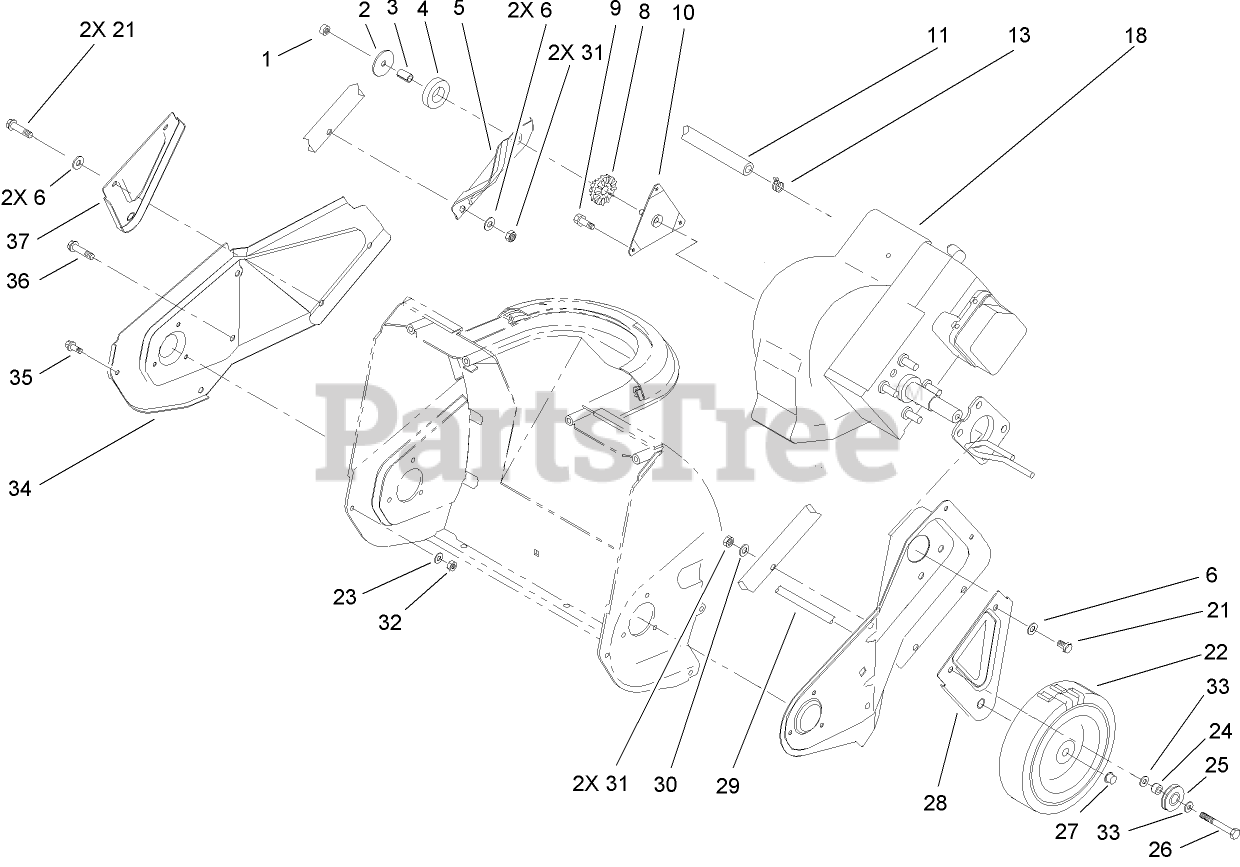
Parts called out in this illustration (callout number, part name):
1	NUT-LOCK, NI
3	SPACER-TUBULAR
4	RING-ISOLATOR
5	BRACKET-SUPPORT, ENGINE
6	WASHER-FLAT
8	BUSHING-ISOLATOR
9	SCREW
10	BRACKET AND STUD ASM
11	HOSE-FUEL
13	CLAMP-HOSE
21	SCREW-HH
22	WHEEL
23	WASHER-FLAT
24	SPACER-BLADE, ROTOR
25	CABLE-PULLEY
26	SCREW-HH
27	NUT-PUSH
28	BRACKET-WHEEL, LH
29	AXLE SHAFT
30	WASHER
31	NUT-LOCK, NI
32	NUT-LOCK, NI
33	WASHER-FLAT
34	PLATE-SIDE, RH
36	SCREW-PLASTIC
37	BRACKET-WHEEL, RH
